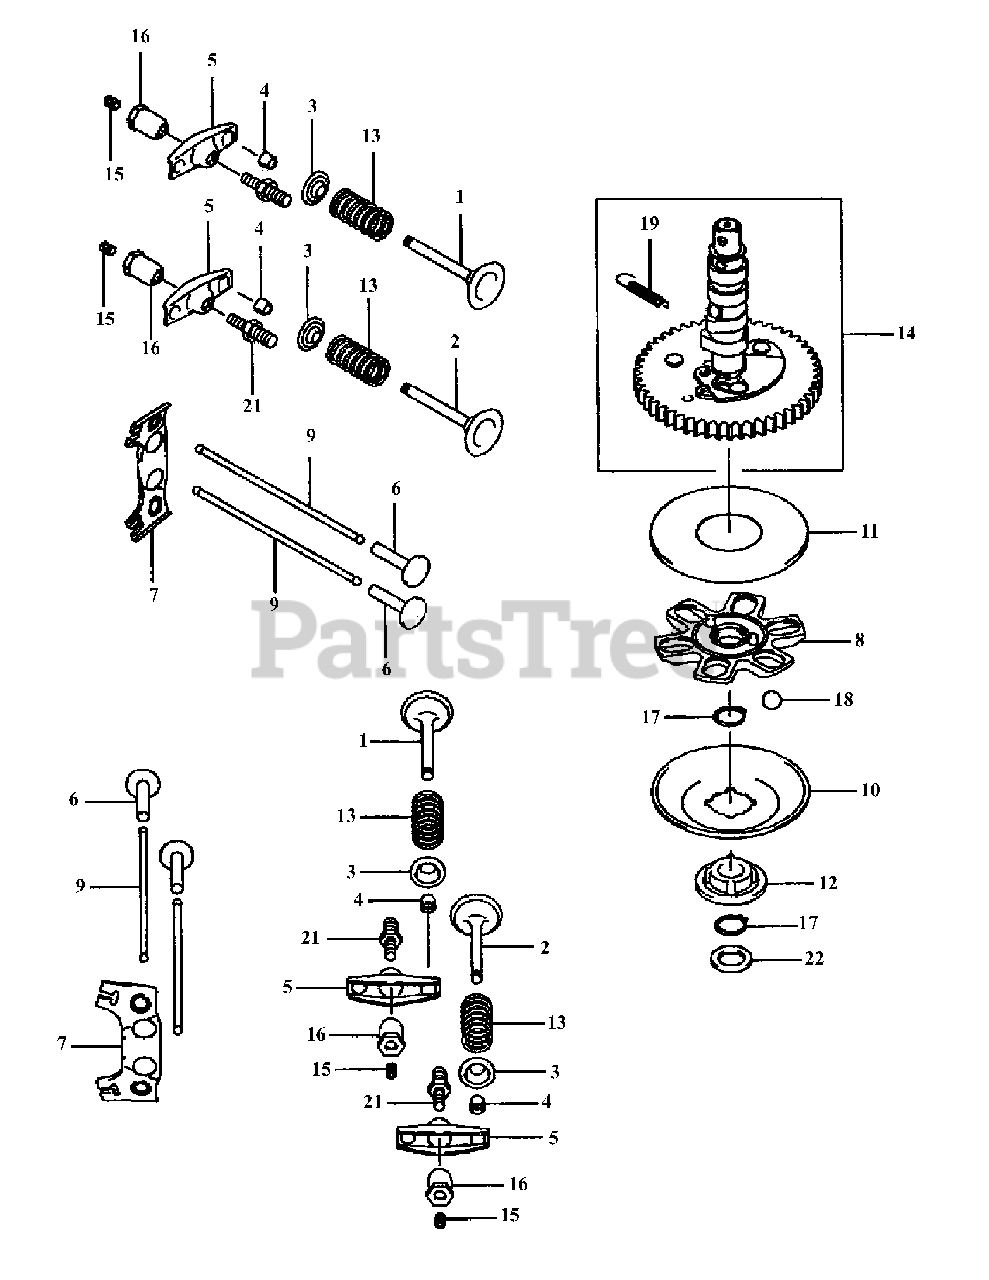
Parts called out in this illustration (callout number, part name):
1	Valve Intake
2	Valve, Exhaust
3	Retainer, Valve Spring
13	Spring, Engine Valve
14	Camshaft, Complete
17	Ring, Snap
18	Ball
19	Spring
